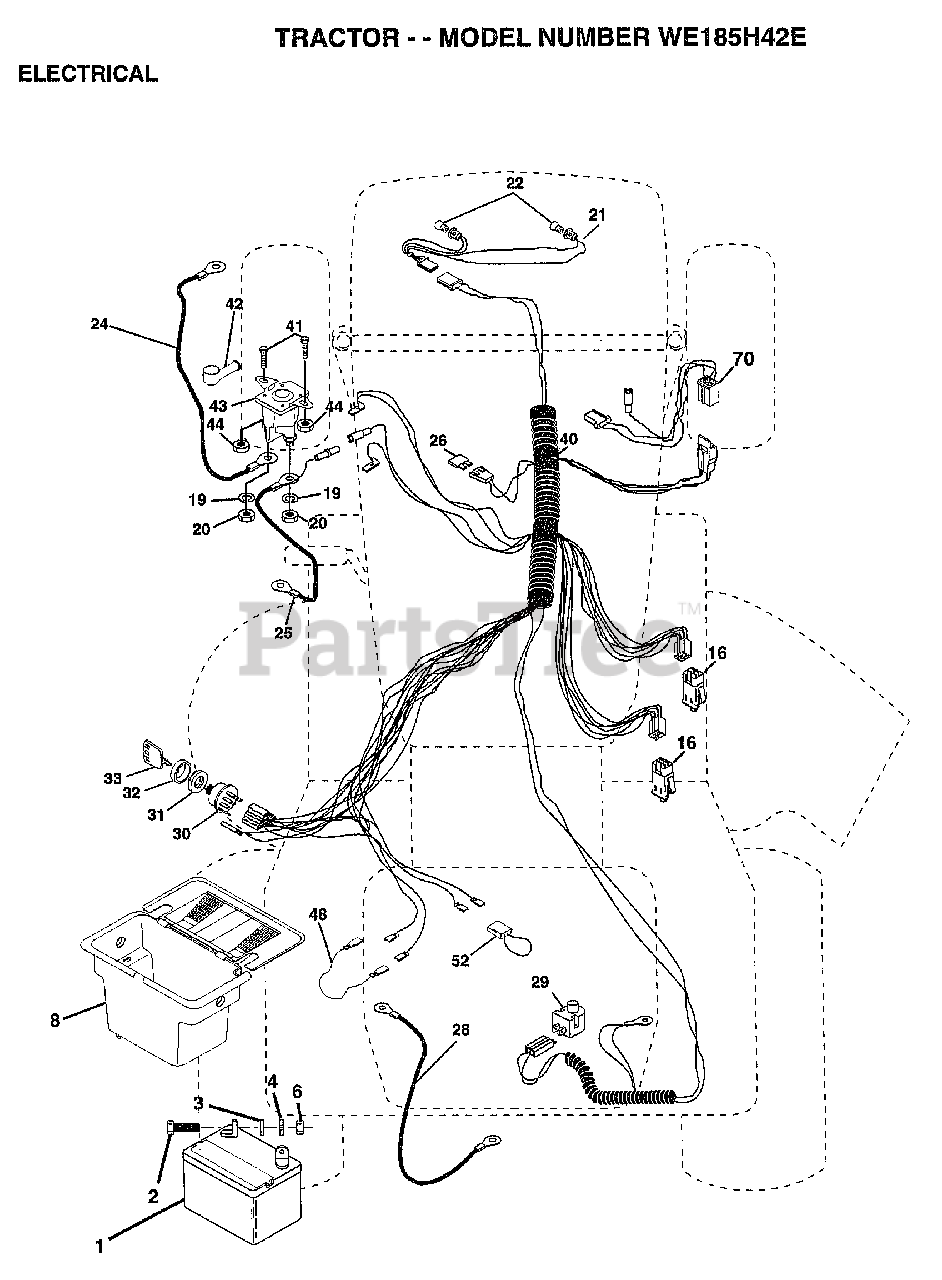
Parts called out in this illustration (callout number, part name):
3	WASHER
4	LOCKWASHER
8	"CASE,BATTERY.MECH"
16	SWITCH INTERLOCK
20	NUT
21	"HARNESS,LIGHT SOC"
22	HEADLAMP BULB
24	"CABLE T, BATTERY"
25	CABLE.BTRY.6GA.RD
26	FUSE HYT
28	CABLE T
29	SWITCH SEAT
30	SWITCH IGN 4POS
31	NUT IGNITION
32	COVER KEY SWITCH
33	KEY
40	HARNESS-IGNITION
41	BOLT HXHD FIN
44	NUT HXKEP 1/4X20
48	ADAPTER AMMETER
52	PROTECTION LOOP
70	HARNESS ENG DUAL
